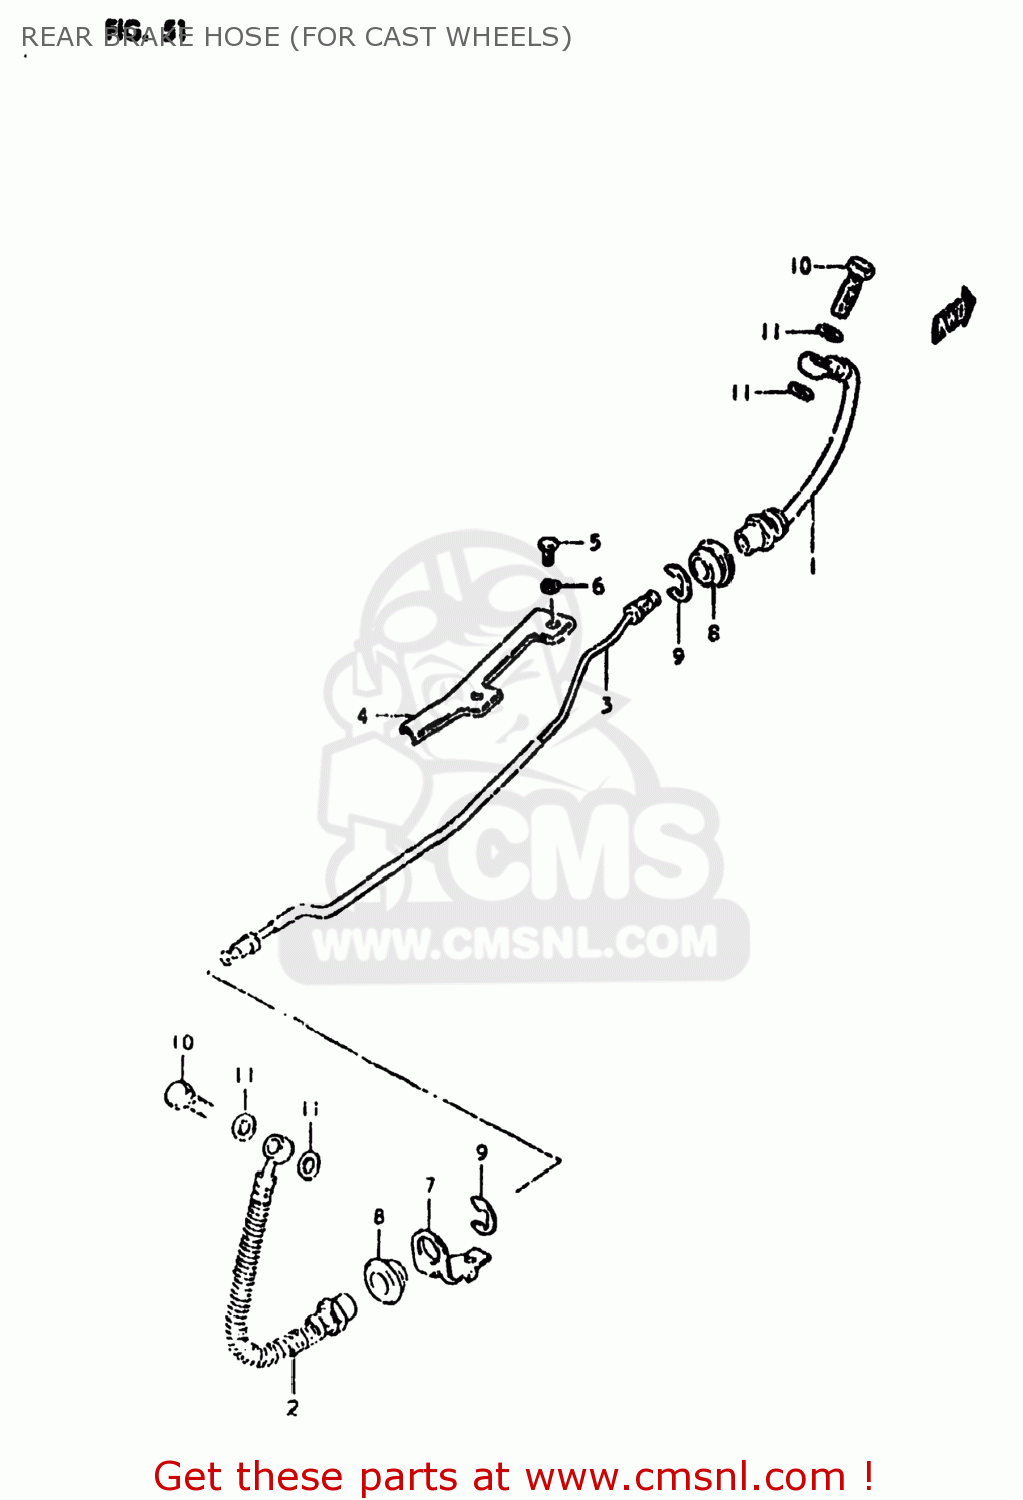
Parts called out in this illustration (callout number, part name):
1	HOSE,REAR BRAKE NO.1
2	HOSE,RR BRAKE NO.2
3	PIPE,REAR BRAKE
4	COVER,REAR BRAKE PIPE
5	BOLT(6X8)
6	LOCK WASHER
7	GUIDE,BRAKE HOSE
8	GROMMET,BRAKE HOSE GUIDE
9	E RING
10	BOLT,UNION
11	WASHER
